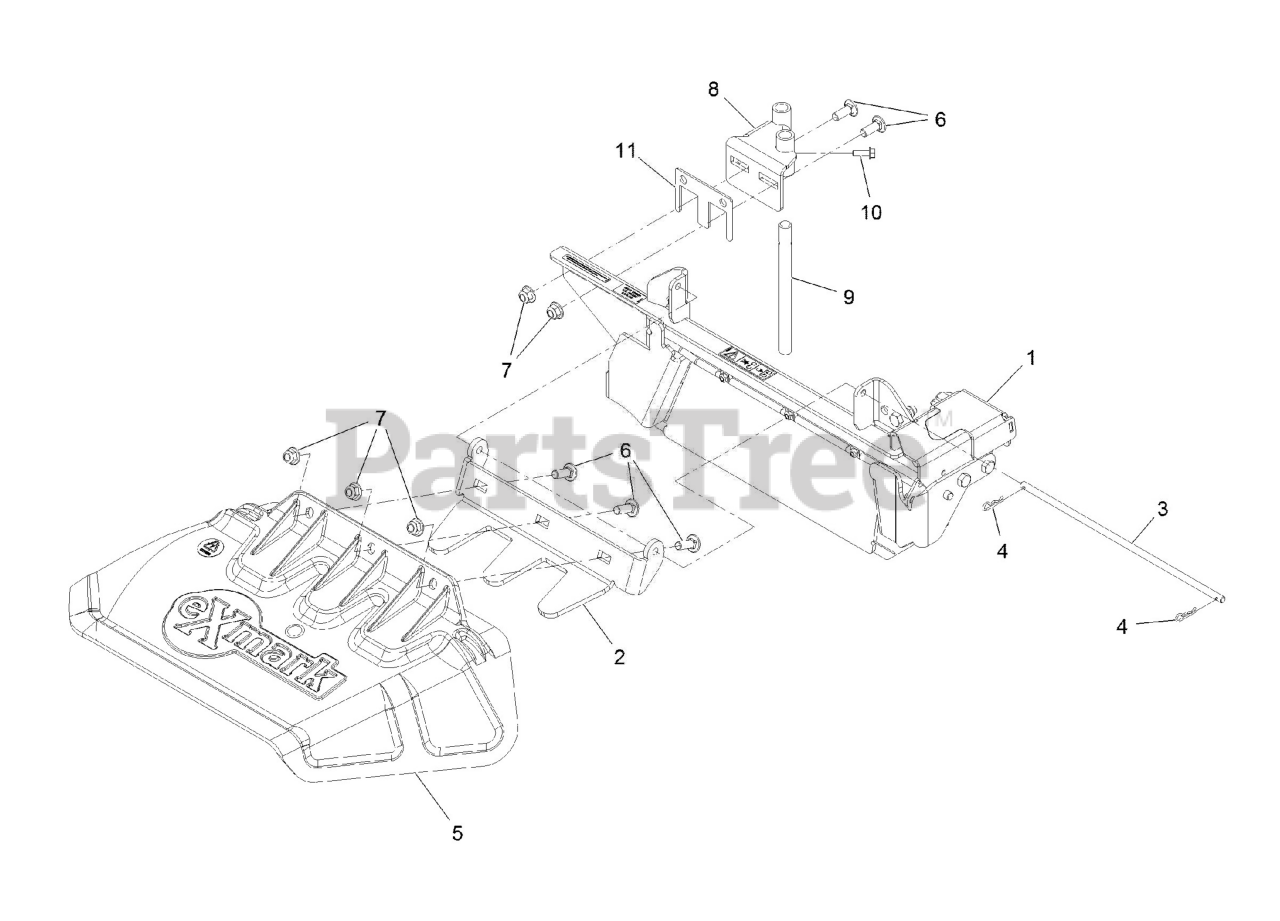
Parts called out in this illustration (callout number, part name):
1	ASM, OCD GATE
2	MOUNT, DISCHARGE CHUTE
3	PIN,CHUTE
4	PIN-COTTER
5	CHUTE,DISCHARGE
6	SCREW-CARR
7	NUT-HF, NI
8	WELDMENT, OCD MOUNT
9	PIN-MOUNT, OCD
10	SCREW-HHF
11	SHIM-OCDWB
